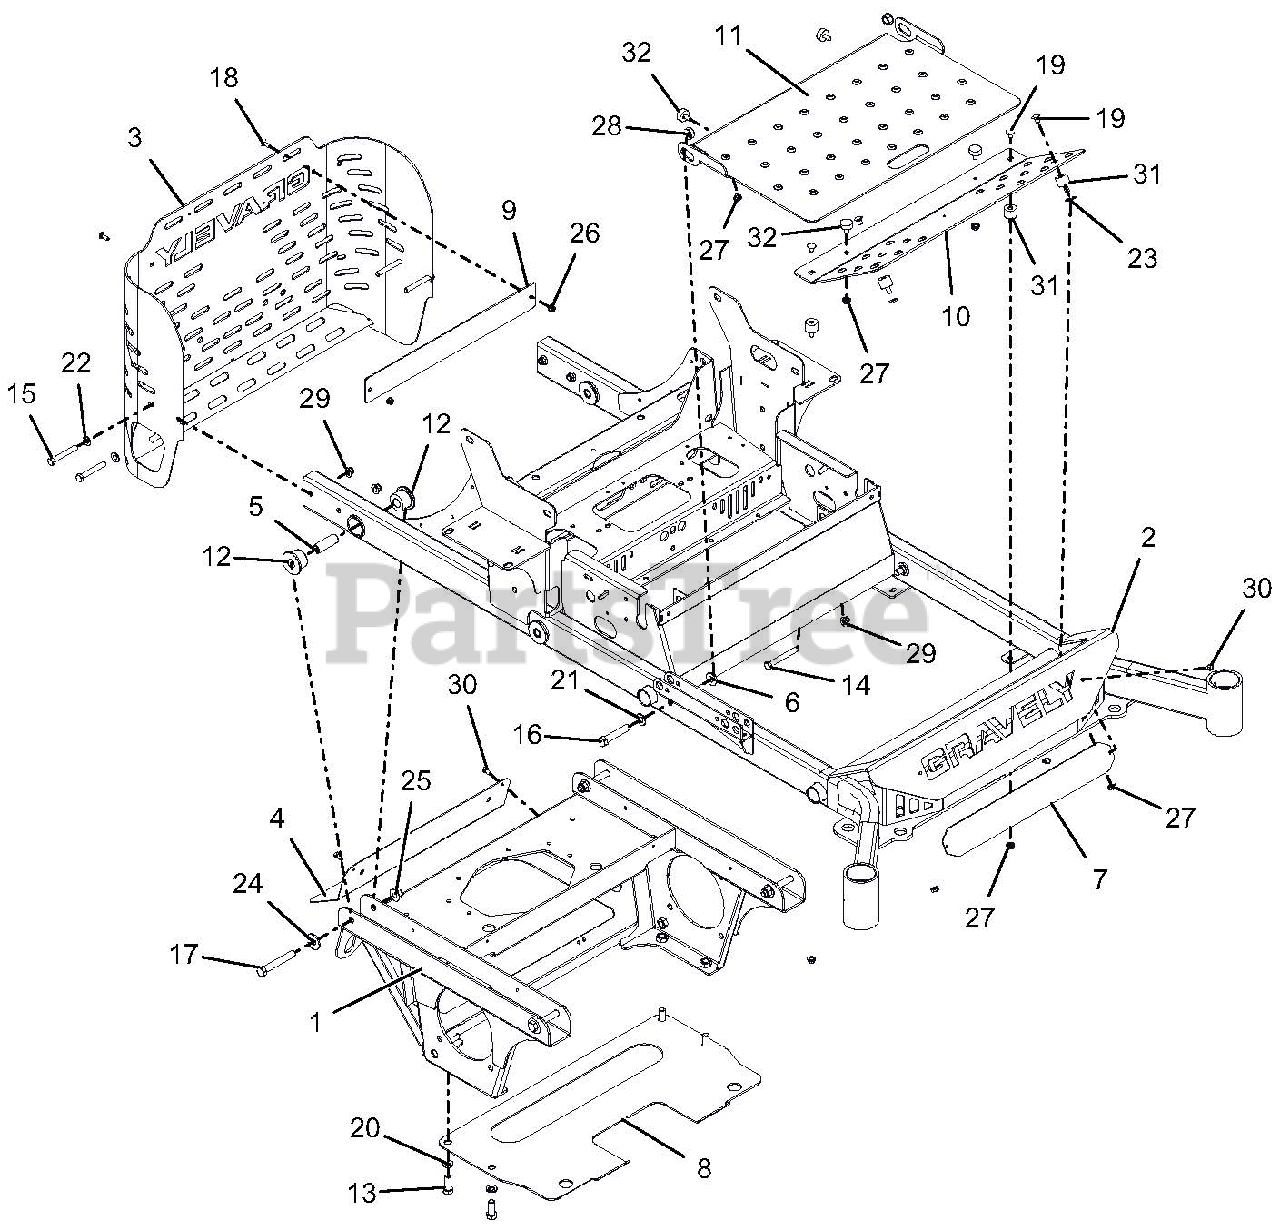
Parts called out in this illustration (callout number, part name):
1	WLDT, 200 PT AXLE/ENGINE FRAME
2	WLDMT, 52-66" PT400 MAIN FRAME-RED
3	WLDMT, PT200 REAR BUMPER
4	SHIELD, MUFFLER HEAT
5	SPCR, .50 X .75 X 2.23 YZ
6	BSHG, FLANGE .515X.750X.31X1.12
7	PLATE, BUMPER LOGO BACKING-BLACK
8	PLATE-TRANSMISSION SKID-RED
9	PLATE, LOGO BACKING
10	WLDMT, FOOTREST
11	WLDMT, FOOTREST
12	BSHG, FLANGE .750 X 1.510 X 1.130 X 2.000
13	BLT-HEX .50-13X1.25 GR5 YWZC
14	BLT-HEX .38-16X3.25 GR5 YWZC
15	BLT-HEX .38-16X2.75 GR5 YWZC
16	BLT-HEX .50-13X2.75 GR5 YWZC
17	BLT-HEX .50-13X3.50 GR5 YWZC
18	BLT-RDHDSQNK .25-20X.75 G5 YWZC
19	BLT-RDHDSQNK .31-18X.50 G5 YWZC
20	WSHR-LK .50X.125 REG YWZC
21	WSHR-FL-STL .531X1.000X.063 YWZC
22	WSHR-FL-STL.406X.812X.065 YWZ
23	WSHR-FL-STL .328X.875X.062 YWZC
24	WSHR-FL-STL.563X1.38X.109YWZC
25	NUT-LK-NYL-FLG .50-13 YWZC
26	NUT-LK-NYL-FLG .25-20 YWZC
27	@NUT-SPNLK-FLG .312-18 YWZC
28	NUT, LK-TOP-FLG .50-13 YWZC
29	NUT-LK-NYL-FLG .38-16 YWZC
30	SCR-TAP .25-20X.50 HWH TR YWZ
31	BUMPER, STUD MOUNTED W/FEMALE INSERT
32	BUMPER, RUBBER
